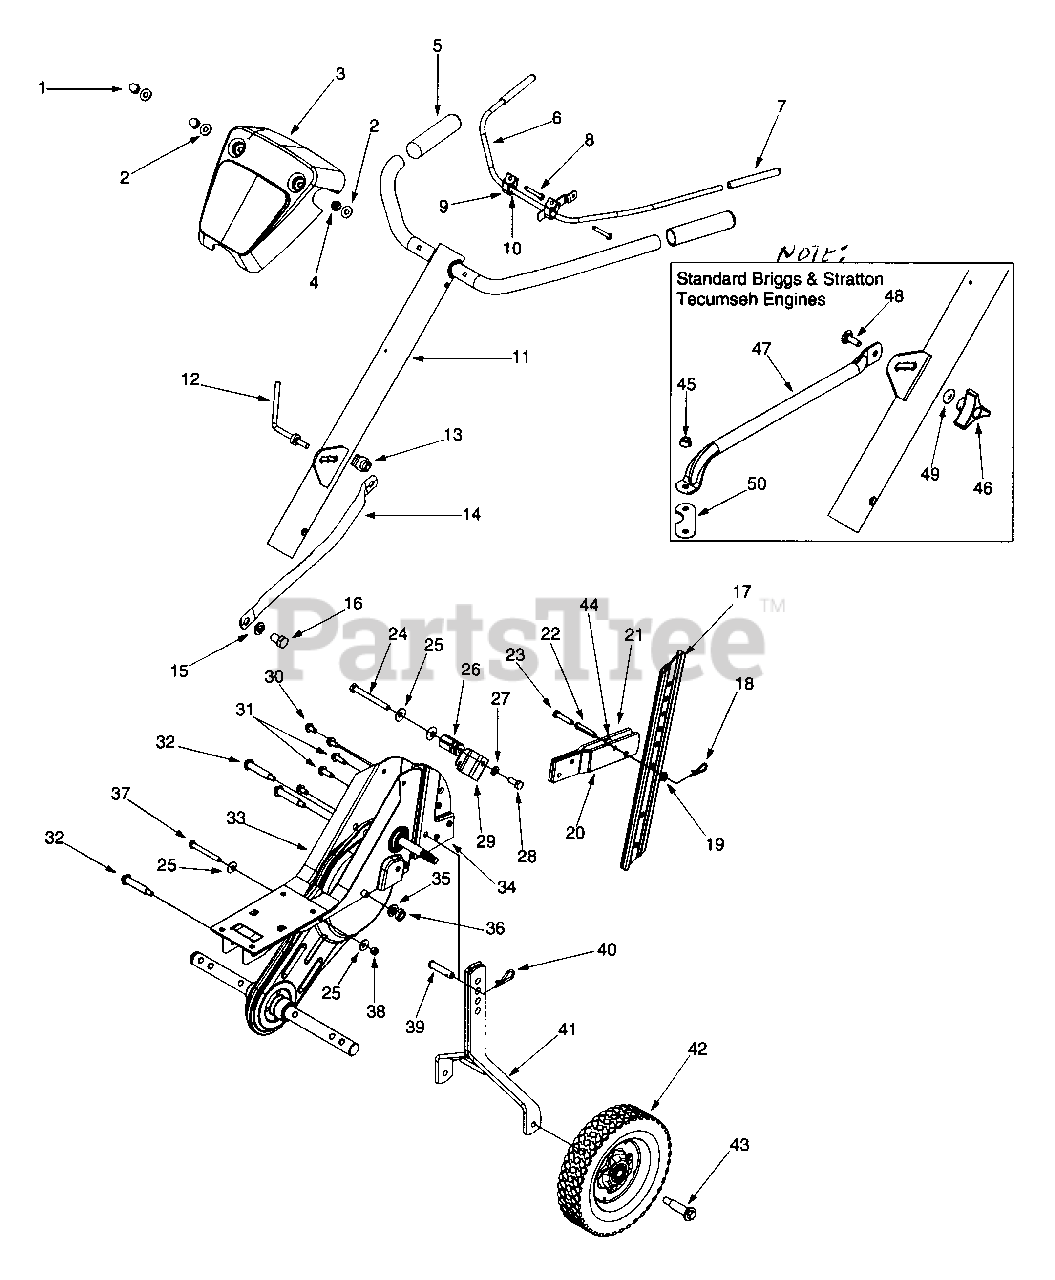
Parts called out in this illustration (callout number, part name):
1	Acorn Lock Nut 1/4-20
2	Flat Washer .271" I.D. x .630"
3	Handle Cover
4	Hex Nut 1/4-20 Gr.2
5	Grip-Handle
7	Grip-Clutch
8	Hex Bolt 1/4-20 x 2.25" Lg. Gr.5
9	Clutch Handle Holder
10	Flat Washer .385" I.D. x .62" O.D.
13	U Nut 5/16-18
16	Hex Bolt 1/2-20 Gr.
18	Cotter Pin
19	Hex Flange L-Nut 5/16-18
22	Clevis Pin
23	Hex Bolt 5/16-18 x 1.5" Lg.
24	Hex Bolt 5/16-18 x 3" Lg.
25	Wash. Bell. .340" I.D. x .872" O.D.
26	Spec. Hex Nut
27	L-Wash. 5/16" I.D.
28	Hex Bolt 5/16-18 Gr. 5
30	Hex Wash Screw 5/16-18 x .62"
31	Hex Wash. Hd. TT-Tap Scr.
32	Shdl. Bolt 5/16-18
35	Lock Washer 7/16
36	Jam Nut 7/16-20 Gr. 2
37	Hex Bolt 5/16-18 x 2.75" Lg.
38	Hex Nyloc Nut 5/16-18 Thd.
39	Clevis Pin
40	Cotter Pin
42	Wheel Ass'y 8" x 1.75"
43	Shoulder Screw .496 x 1.445
44	Spacer
45	Hex Flange L-Nut 5/16-18 Thd.
46	Hand Knob
49	Bell. Wash. .34" I.D.
50	Engine Brkt. (Std B&S)
